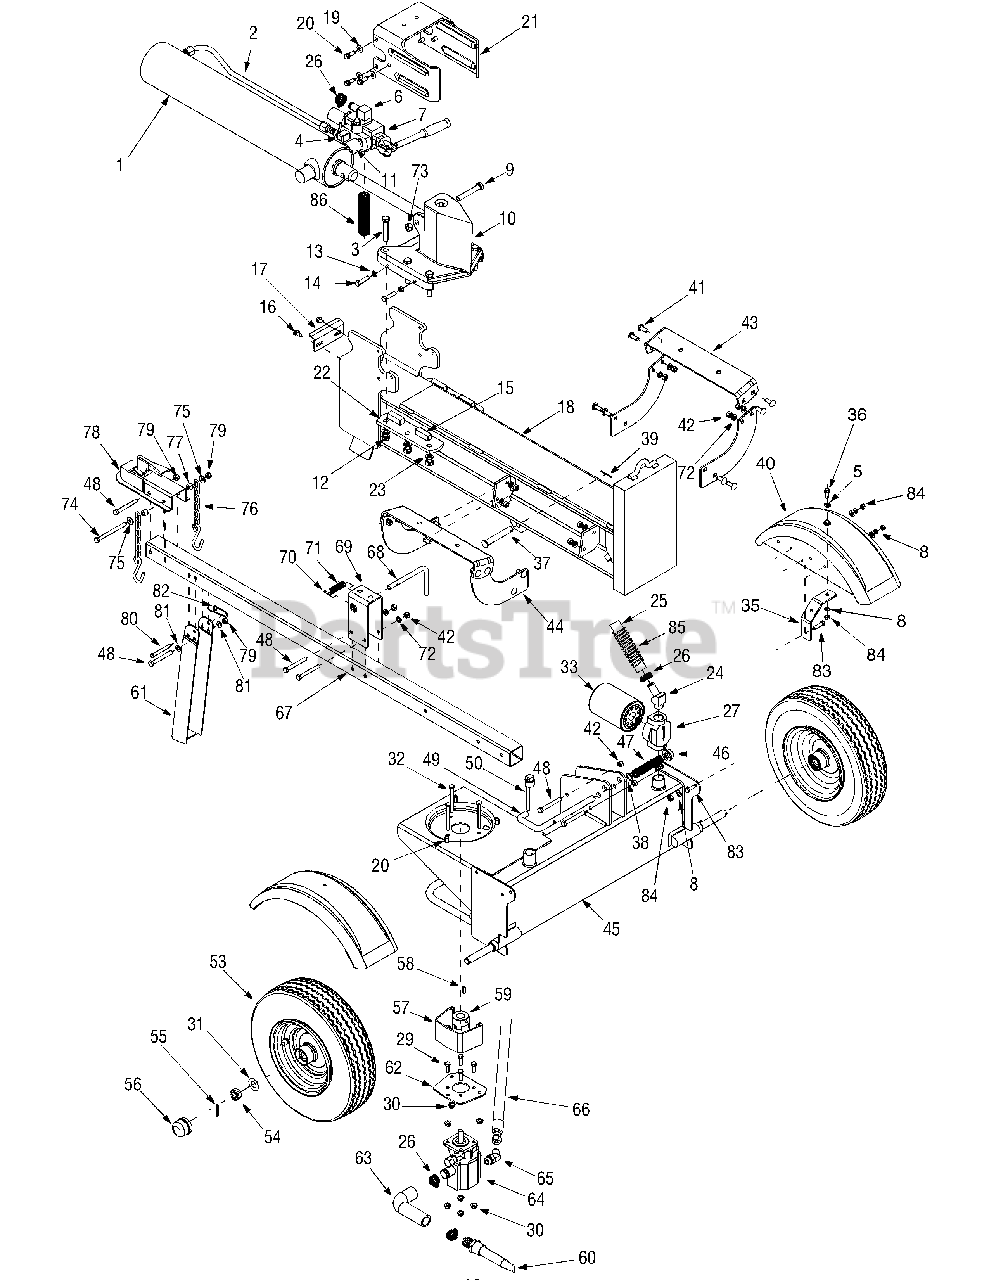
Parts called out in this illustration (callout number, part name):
1	Hydraulic Cylinder
1	Seal Kit 4.5" for Fisher Cylinder 718-0769
1	Kit Seal 4.5" for XINGHUI cylinder 718-0769A
1	Kit Seal 4.5" for ENERGY cylinder 718-0769A
2	Hydraulic Tube
3	Hex Cap Screw 1/2-20 x 2.75
4	90° Solid Adapter
5	Flat Washer, .434 x .880 x .062
6	Return Elbow
8	Lock Washer, 5/16
9	Hex Cap Screw 1/2-13 x 3.25
10	Wedge Assembly
11	Nipple Pipe 1/2-14
12	Lock Nut 1/2-20
13	Hex Jam Nut 3/8-24
14	Hex Cap Screw 3/8-24 x 1.5
16	Screw 5/16-18 x.75
19	Flat Washer.406 ID x.875 OD
20	Hex Washer Screw 3/8-16 x 1.0
23	Lock Washer 1/2
24	Adapter 3/4-14
25	Return Hose 3/4" ID x 44"
26	Hose Clamp 5/8"
27	Filter Housing
28	Hex Screw, 5/16-18 x 1.25
29	Hex Screw , 5/16-18 x 1.0
30	Hex Flange Nut, Nylon, 5/16-18
31	Flat Washer.760 ID x.500 OD
32	Hex Bolt 5/16-18 x 3.25"
33	Oil Filter
36	Hex Screw, 5/16-18 x .875
37	Clevis Pin
38	Flat Washer.635 ID x.93 OD
39	Cotter Pin
40	Fender, Black
41	Carriage Bolt 3/8-16 x 1.0
42	Hex Flange Lock Nut 3/8-16
46	Push Cap
47	Compression Spring
48	Hex Bolt 3/8-16 x 3.25"
49	Lock Rod
50	Vented Dipstick
51	Hex Screw 5/16-24 x 3.25
53	Wheel Assembly
54	Slotted Nut 3/4-16
55	Cotter Pin
56	Hub Cap
57	Coupling Shield
58	Square Key 3/16" x.75
59	Flexible Coupling
60	Inlet Filter
64	Gear Pump
65	45° Elbow
66	High Pressure Hydraulic Hose
68	Tongue Latch Rod
70	Spiral Pin
71	Compression Spring
72	L-Washer 3/8"
73	Hex Lock Nut 1/2-13
74	Hex Cap Screw 3/8-16 x 4.25
75	Flat Washer.385 ID x.870 OD
76	Chain
77	Spacer.375 ID x.625 OD
78	Hitch Coupler
79	Hex Lock Nut 3/8-16
80	Clevis Pin
81	Flat Washer.375 ID x.738 OD
82	Spring Pin
83	Hex Screw, 5/16-18 x .875
84	Hex Nut, 5/16-18
85	Hose Guard
86	Hose Guard
